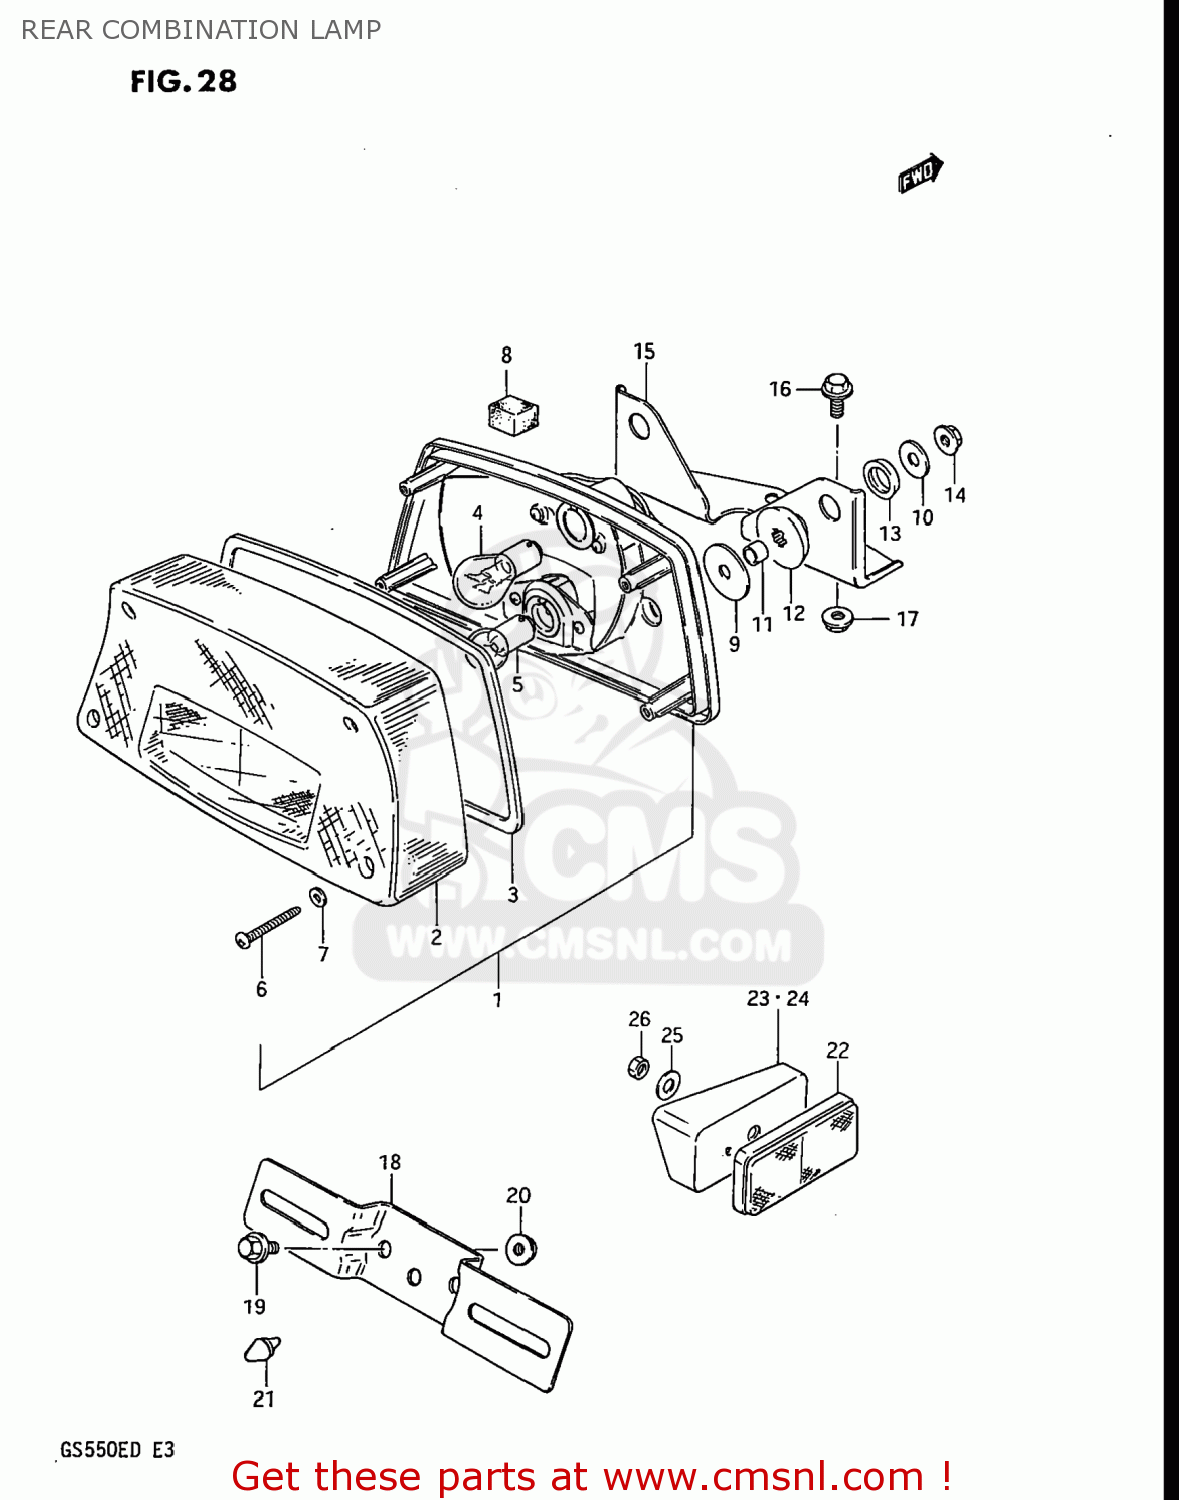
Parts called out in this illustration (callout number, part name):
1	LAMP ASSEMBLY,REAR COMBINATION
2	LENS
3	GASKET
4	BULB(12V23W)
5	BULB
6	SCREW ,4X25
7	GASKET (NAS)
8	CUSHION,REAR COMBINATION LAMP
9	WASHER(6.5X30X1.2)
10	WASHER(6,5X22X1.6)
11	SPACER (6.8X10X11.5)
12	CUSHION
13	CUSHION
14	NUT 6MM
15	BRACKET,REAR COMBINATION LAMP
16	BOLT
17	NUT 6MM
18	BRACKET,LICENSE PLATE
19	BOLT
20	NUT 6MM
21	CUSHION
22	REFLECTOR,REFLEX
23	SPACER,REAR REFLECTOR,RIGHT
24	SPACER,REAR REFLECTOR,LEFT
25	WASHER(5.2X16X1)
26	NUT
